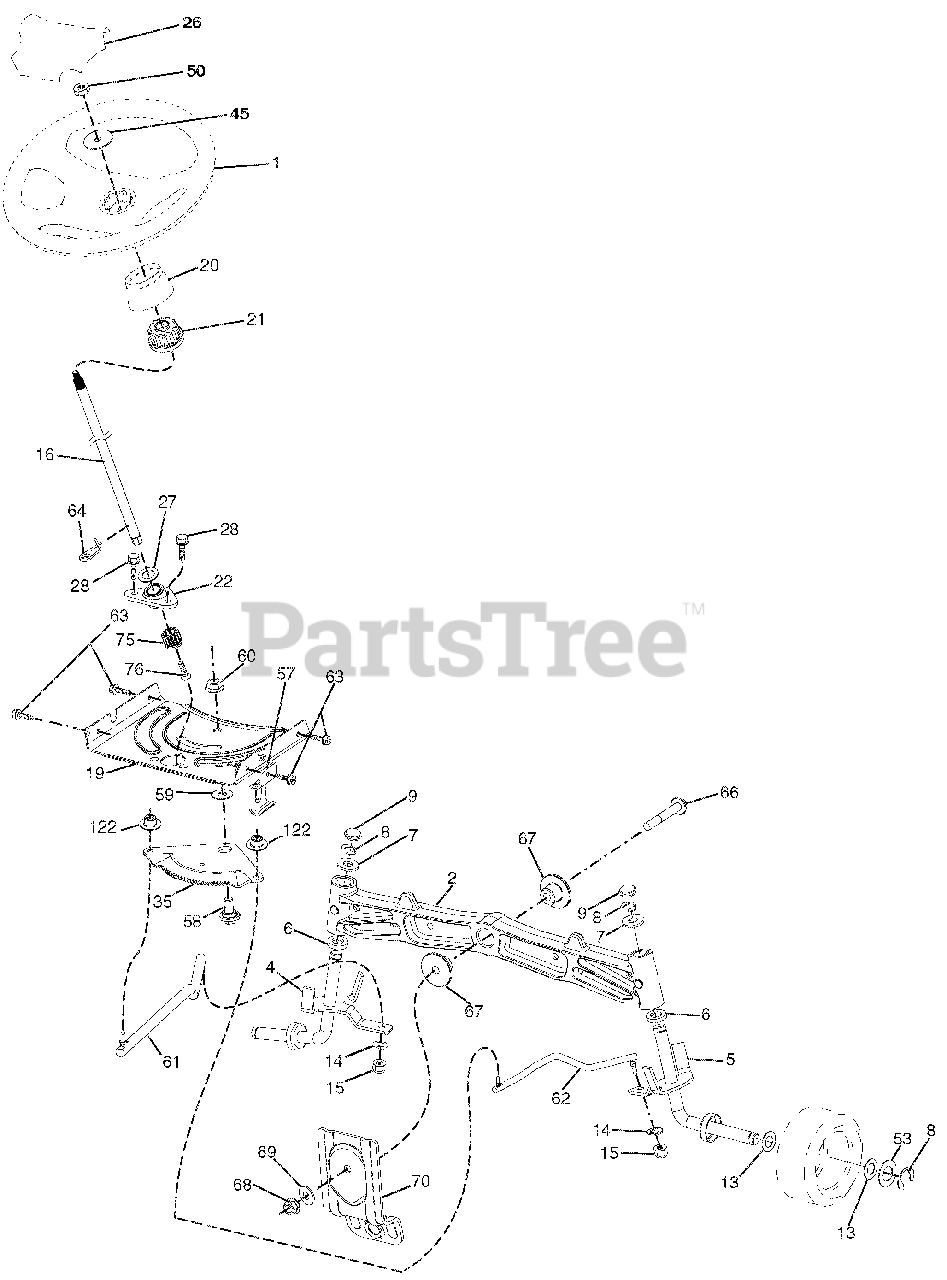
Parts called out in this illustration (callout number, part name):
1	WHEEL STEERING
2	AXLE.CAST IRON
4	SPINDLE.WELDED.LH.15"TEX
5	SPINDLE.WELDED.RH.15"TEX
6	WAHSER THRUST .75 X 1.230
7	WASHER.25/32 X 1-5/8 X 16GA.
8	RING.KLIP.#T5304-75
9	CAP.SPINDLE.FR.TOP.BLK.
13	WASHER.25/32 X 1 1/4 X 16 GA.
14	Washer, Lock 3/8
15	NUT.CROWNLOCK.3/8-24
16	SHAFT STEER
19	PLATE.STEER.DDL.NLT/NGT
20	BOOT.STEERING
21	ADAPTER.STEER
22	STEER.SUPT. LOWER
26	CAP WHEEL STEERING HRS/SRS BLK
27	WASHER 21/32 X 1 X 1 GA.
28	SCREW.HEXWSH THDR3/8-16X3/4.BL
35	GEAR SECTOR.PLATE.DDL.NLT/NGT
50	Nut, Hex, Flangelock 3/8-16
53	WASHER.HARDEN..793 X 1.637X060
57	BRACKET.UPSTOP.GT/LT.TEX
58	BOLT.SHOULDER.SECTOR.PIVOT.CFM
59	WASHER.THRUST.SECTOR.STEER.NLT
60	NUT.FLANGE LOCK.5/8-11
61	DRAGLINK.LH.BALLSTUD.DDL.
62	DRAGLINK.RH.BALLSTUD.DDL
63	SCREW.5/16-18X3/4.SMGML.TAP/BL
64	RETAINER.CLIP.SPRING.STEERING
66	BOLT.HEX.FGHD.7/16-14 X 3.SERR
67	BUSHING.PM.FRONT AXLE
68	NUT.LOCK.FLANGE.7/16-14.GR5
69	WASHER.1.5 X .505 X .118
70	BRACKET.DECK.SUSPENSION.FRONT
75	PINION
122	CAP GEAR SECTOR
